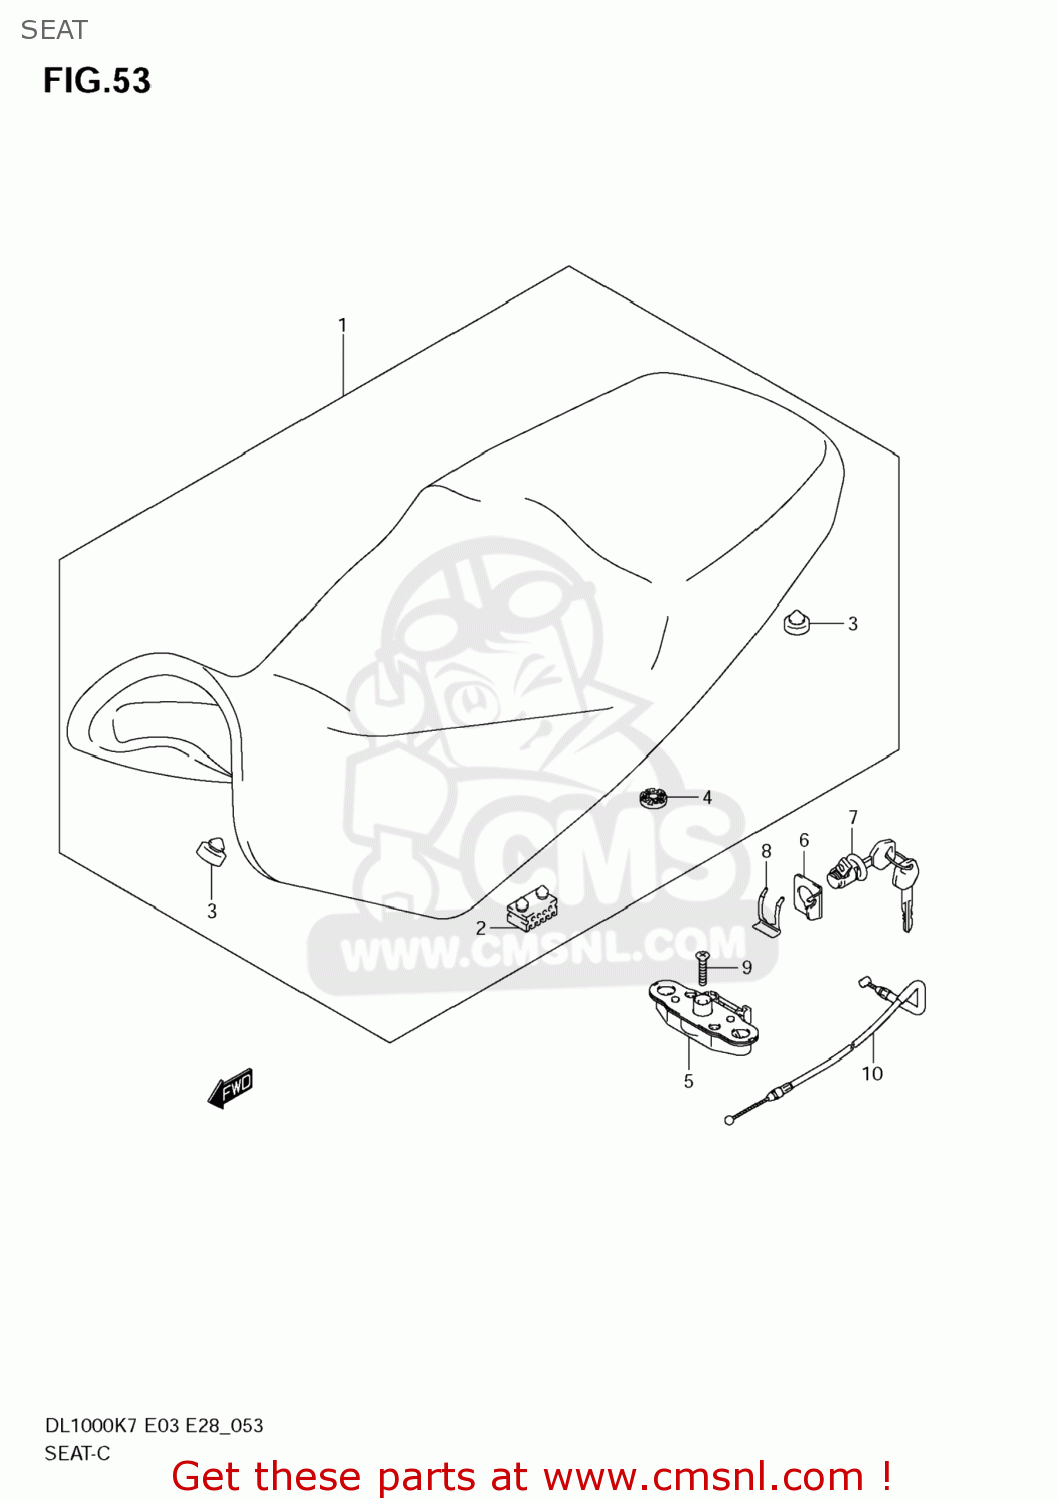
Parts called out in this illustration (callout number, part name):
1	SEAT ASSY
2	CUSHION
3	CUSHION
4	CUSHION,SEAT LOCK(10X22X6)
5	BRACKET,SEAT SUPPORT,RIGHT
6	GUIDE,SEAT LOCK CABLE
7	LOCK SET,SEAT
8	PLATE,SEAT LOCK ASSY
9	SCREW
10	CABLE,SEAT LOCK
